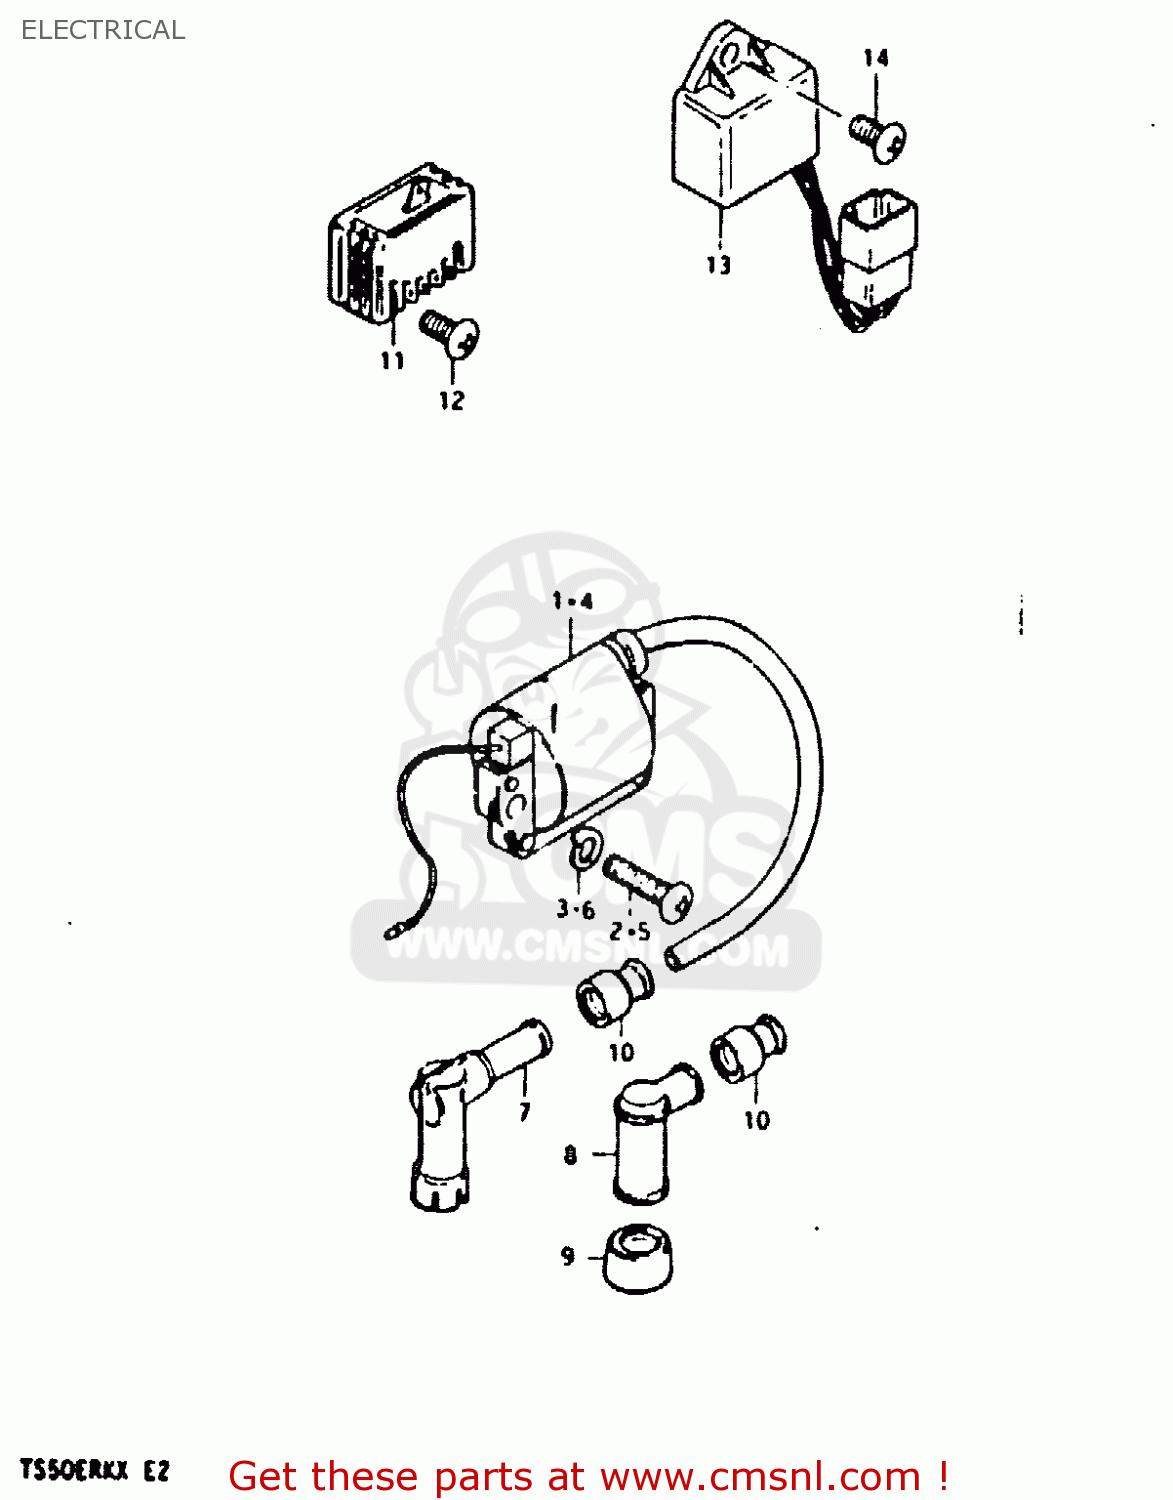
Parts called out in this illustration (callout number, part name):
1	COIL ASSEMBLY,IGNITION
2	SCREW
3	LOCK WASHER
7	CAP,SPARK PLUG
10	SEAL,SPARK PLU
